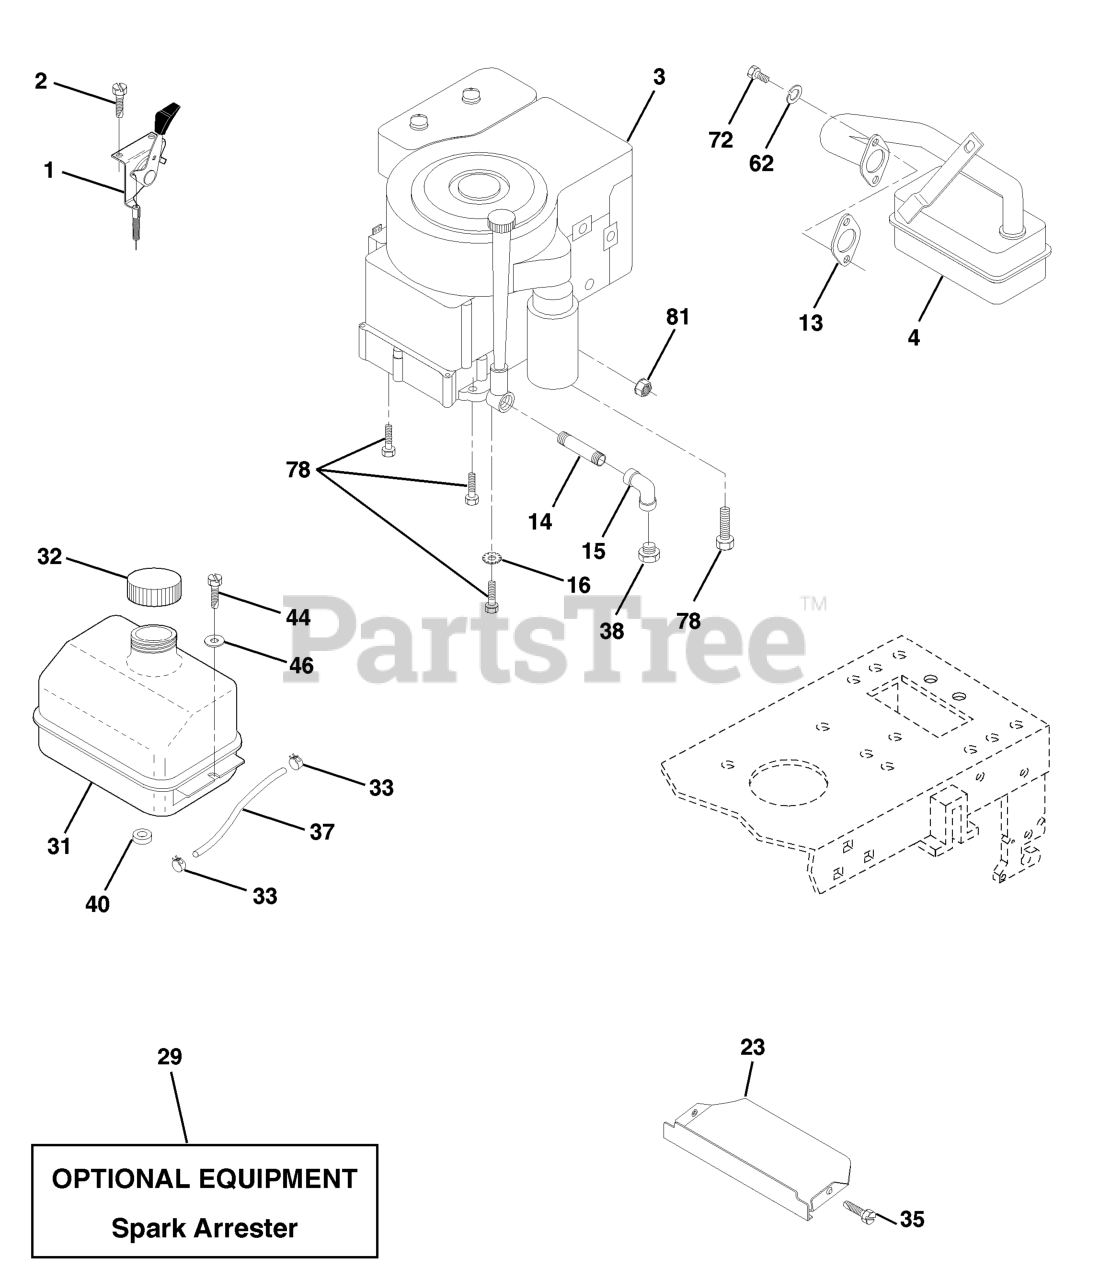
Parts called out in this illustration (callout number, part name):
1	CHOKE CONTROL
2	SCREW LT
4	MUFFLER.SINGLE.B&S.10-12HP
13	GASKET.ENG.1.313 ID.TIN PLATED
14	Nipple Pipe 3/8 Npt X 3"
15	ELBOW
16	LOCKWASHER
29	KIT.SPARK ARRESTOR 794945 B&S
31	TANK FUEL LT
32	FUEL CAP
33	HOSE CLAMP
35	SCREW.THDROL.5/16-18X3/4.TTY
37	LINE.FUEL.20
38	Oil Drain Plug
40	BUSHING.SNAP.NYL.BLK.
44	SCREW HEX CRT
46	WASHER
62	WASHER.LOCK.HVY.HLCL.SPR.5/16
72	SCREW
78	SCREW
81	NUT FLANGE 1/4-20 STARTER NUT
